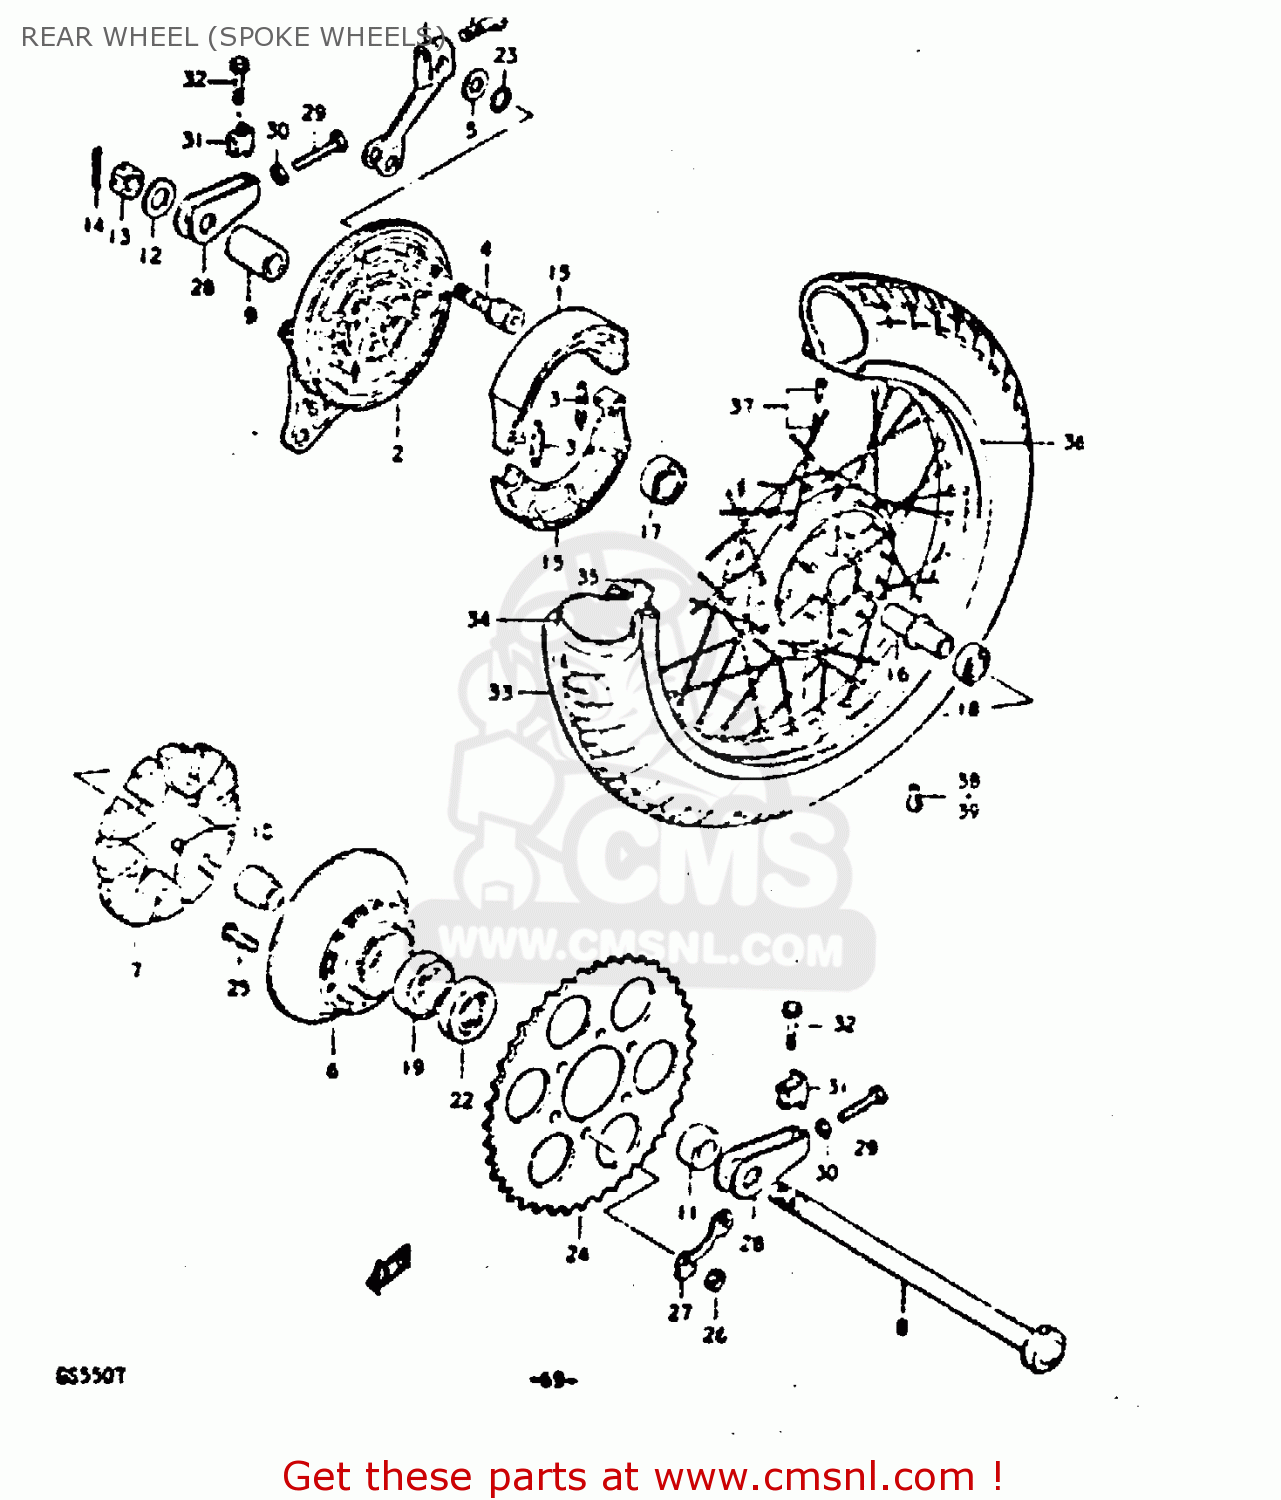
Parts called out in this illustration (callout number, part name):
1	DRUM,REAR HUB
2	PANEL,REAR HUB
3	SPRING,BRAKE SHOE
4	CAM,FRONT BRAKE
5	WASHER (15X24X1.6)
6	DRUM,REAR SPROCKET MOUNT
7	CUSHION,REAR DRUM
8	AXLE,REAR
9	SPACER (17.5X28X51.8)
10	SPACER,REAR HUB BEARING
11	SPACER(17X30.5X22.3)
12	WASHER (17X30X3.2)
13	NUT
14	PIN,COTTER
15	SHOE,BRAKE
16	SPACER
17	BEARING
18	BEARING
19	BEARING
20	LEVER,RR BRAKE CAM
21	BOLT
22	OIL SEAL
23	O-RING,BOSS
24	SPROCKET,REAR
25	BOLT
26	NUT
27	WASHER
28	ADJUSTER,CHAIN
29	BOLT
30	NUT
31	SUPPORTER,CHAIN ADJUST
32	BOLT
33	TIRE
34	TUBE,INNER
35	PROTECTOR
36	RIM,WHEEL
37	SPOKE SET,REAR
38	BALANCER,WHEEL (B)
39	BALANCER,WHEEL (30G)
